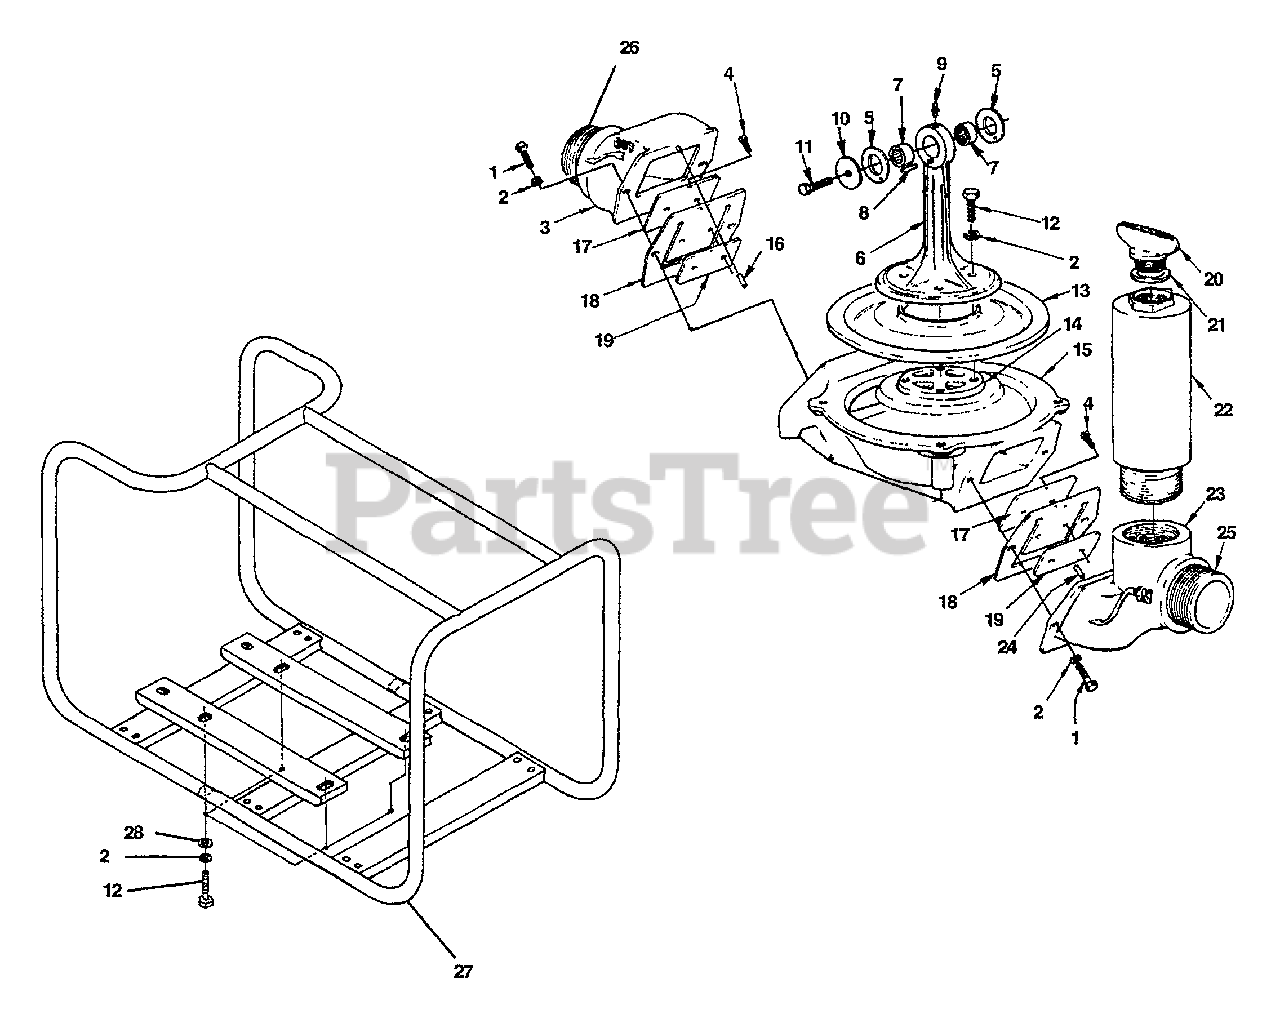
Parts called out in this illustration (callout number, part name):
1	SCREW, Hex hd. (1/2-13 X 1 3/4)
2	WASHER, Lock (1/2")
3	FITTING-Discharge
4	SCREW, fil hd., 10-32 x 1/2
5	WASHER, thrust
6	PUMP ROD
7	BEARING, needle
8	PIN-Coiled spring
9	GREASE FITTING
11	SCREW, hex hd., 3/8-16 x 3/4
12	SCREW, hex hd., 1/2-13 x 1 1/4
13	DIAPHRAGM
14	PLATE, diaphragm
15	PUMP BODY
16	PIN-Roll
17	VALVE, plate
18	VALVE, flapper
19	WEIGHT, valve
20	PLUG-Wing
21	PLUG GASKET
22	STANDPIPE-3"
23	SUCTION FITTING
24	PIN, roll
25	NIPPLE - 3"
26	NIPPLE - 3"
27	ROLL CAGE
28	WASHER FLAT 1/2"
